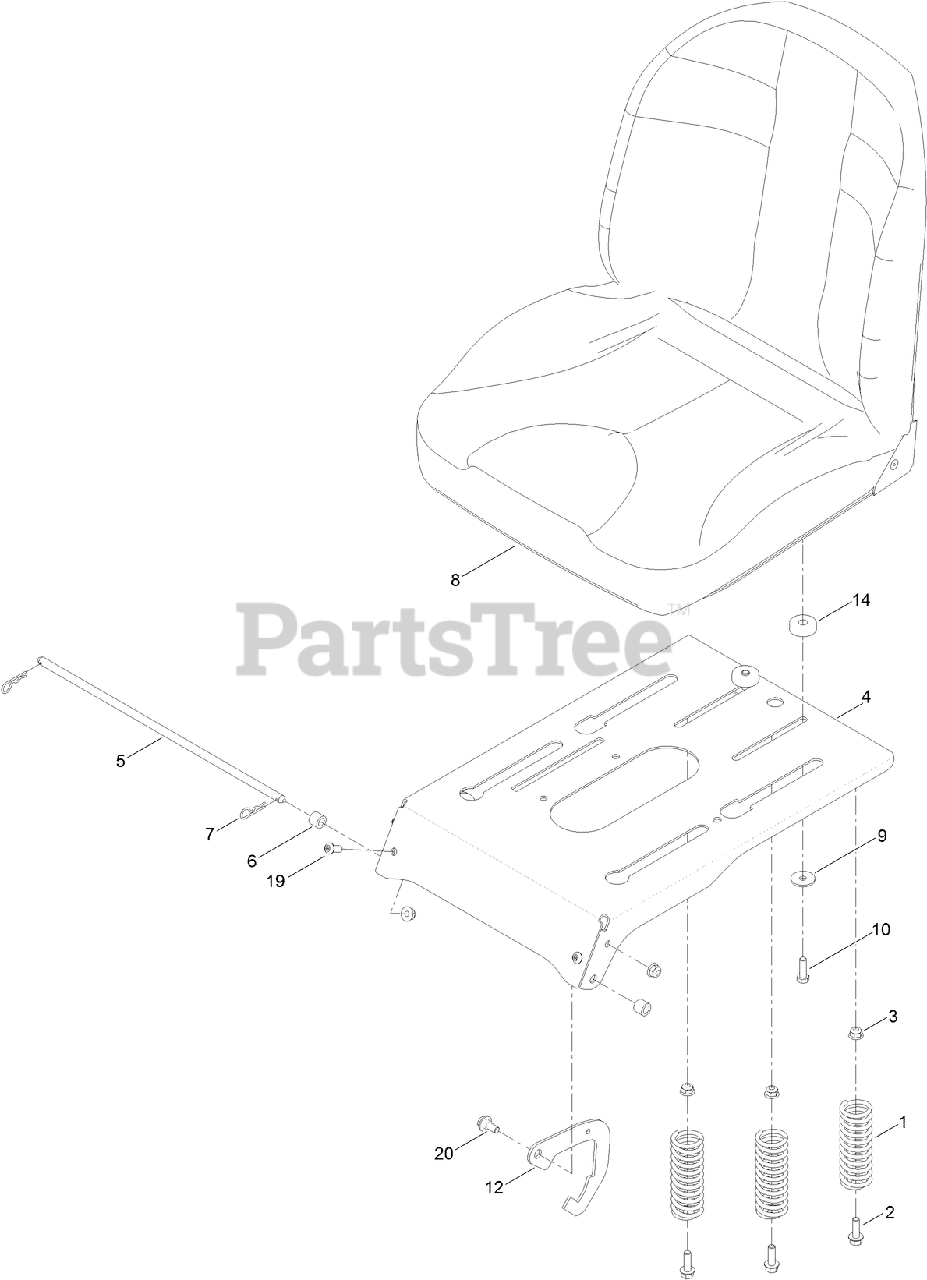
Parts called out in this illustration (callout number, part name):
1	SPRING-COMPRESSION
2	SCREW-HHF
3	NUT-HF, NI
4	PAN-SEAT, DELUXE
5	ROD-STOP
6	BUSHING-LEVER, LIFT
7	PIN-COTTER
9	WASHER-PIVOT
10	SCREW-HH
12	LATCH-SEAT
14	BUSHING-SLIDE, SEAT
19	SCREW-HSBH
20	SCREW-SHOULDER
